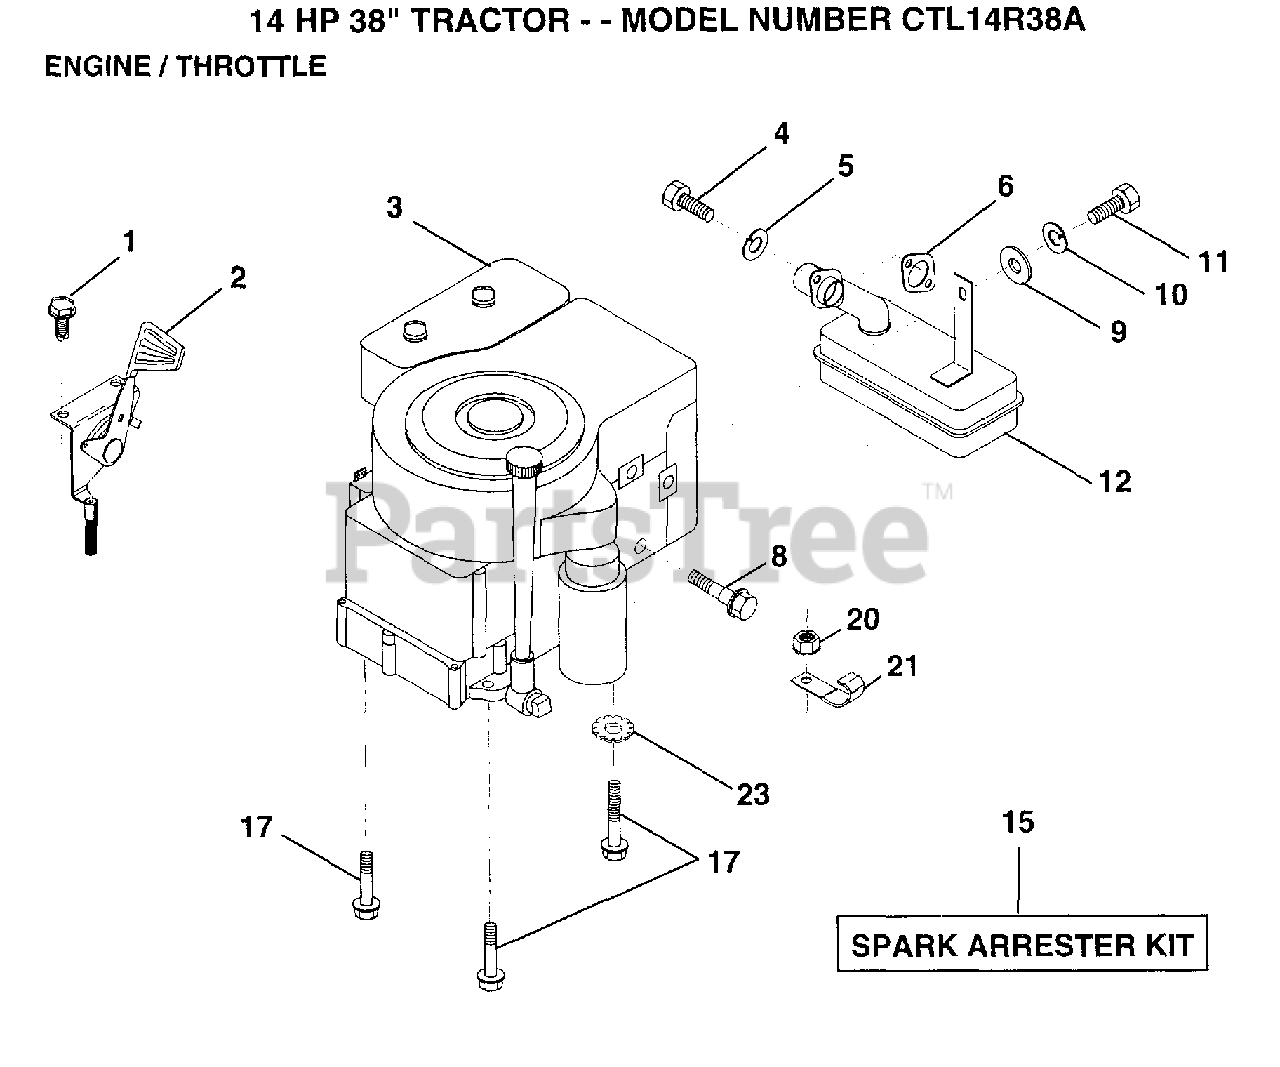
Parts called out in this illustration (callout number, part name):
1	SCREW.1/4-20X1/2
2	"CONTROL,THROTTLE"
4	SCREW
5	LOCKWASHER
8	BOLT T
9	WASHER.5/16X3/4
10	LOCKWASHER
11	SCREW.1/4-20
12	MUFFLER.VANGUARD
17	SCREW LT
20	NUT
21	CLIP T
23	LOCKWASHER
